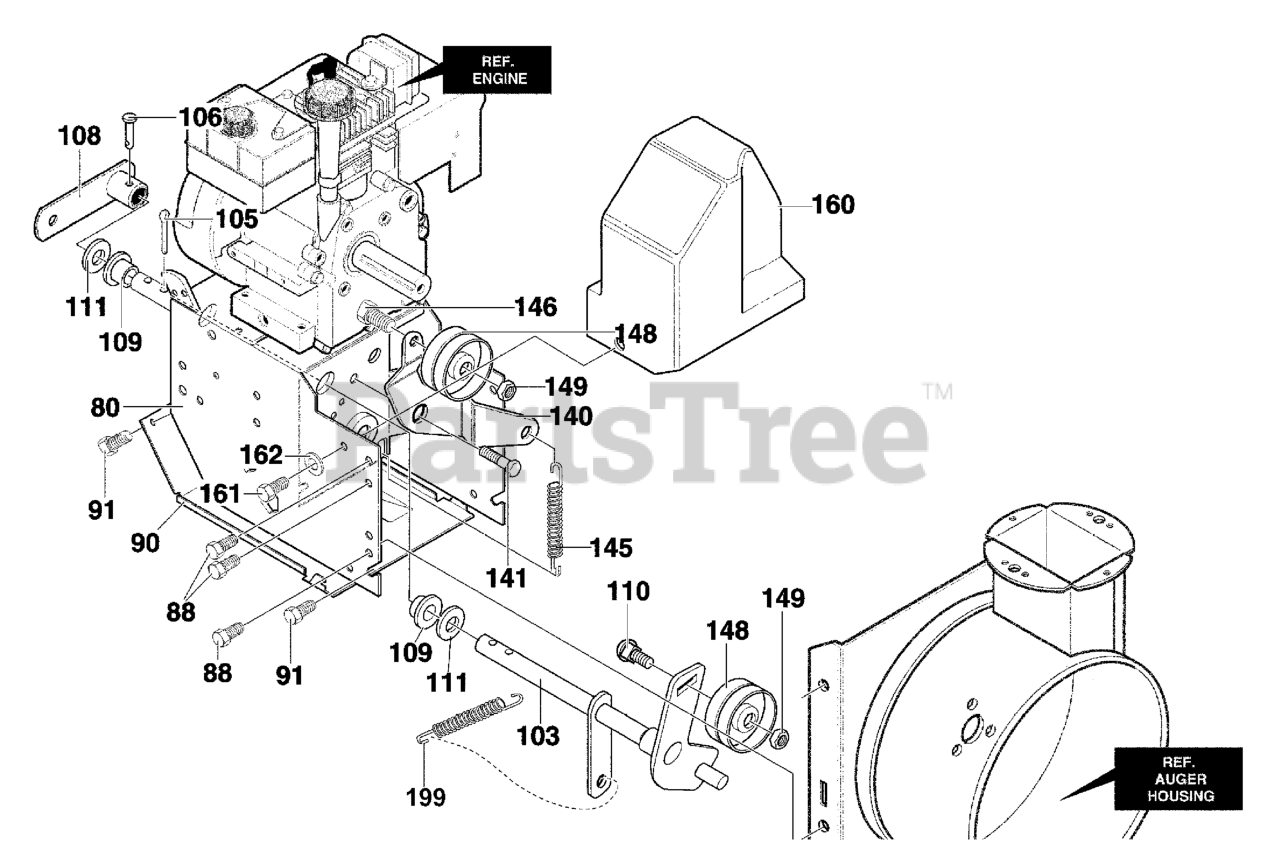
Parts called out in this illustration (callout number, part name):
80	FRAME ASSY
88	SCREW, 5/16-18 x 0.50
90	COVER, BOTTOM
91	SCREW, 1/4-20X .63
103	IDLER ASSEMBLY
105	PIN, HAIR .38DIAX1.64LG
106	PIN, KLIK 3/16" DIA
108	ASSY., SPRING ATTACH
109	BEARING, FL.
110	BOLT, 3/8-16X1.25 CARR.
111	WASHER, FLAT
140	LEVER, IDLER ARM TRACTION
141	BOLT, .625X.135 HHSH 5/16-18
145	IDLER SPRING TRACTION DRIVE
146	SCREW, 3/8-16 x 1.25
148	PULLEY, IDLER
149	NUT, 3/8-16
160	COVER, BELT
161	SCREW, 1/4-20X .63
162	WASHER, FLAT
199	SPRING, IDLER AUGER DRIVE
